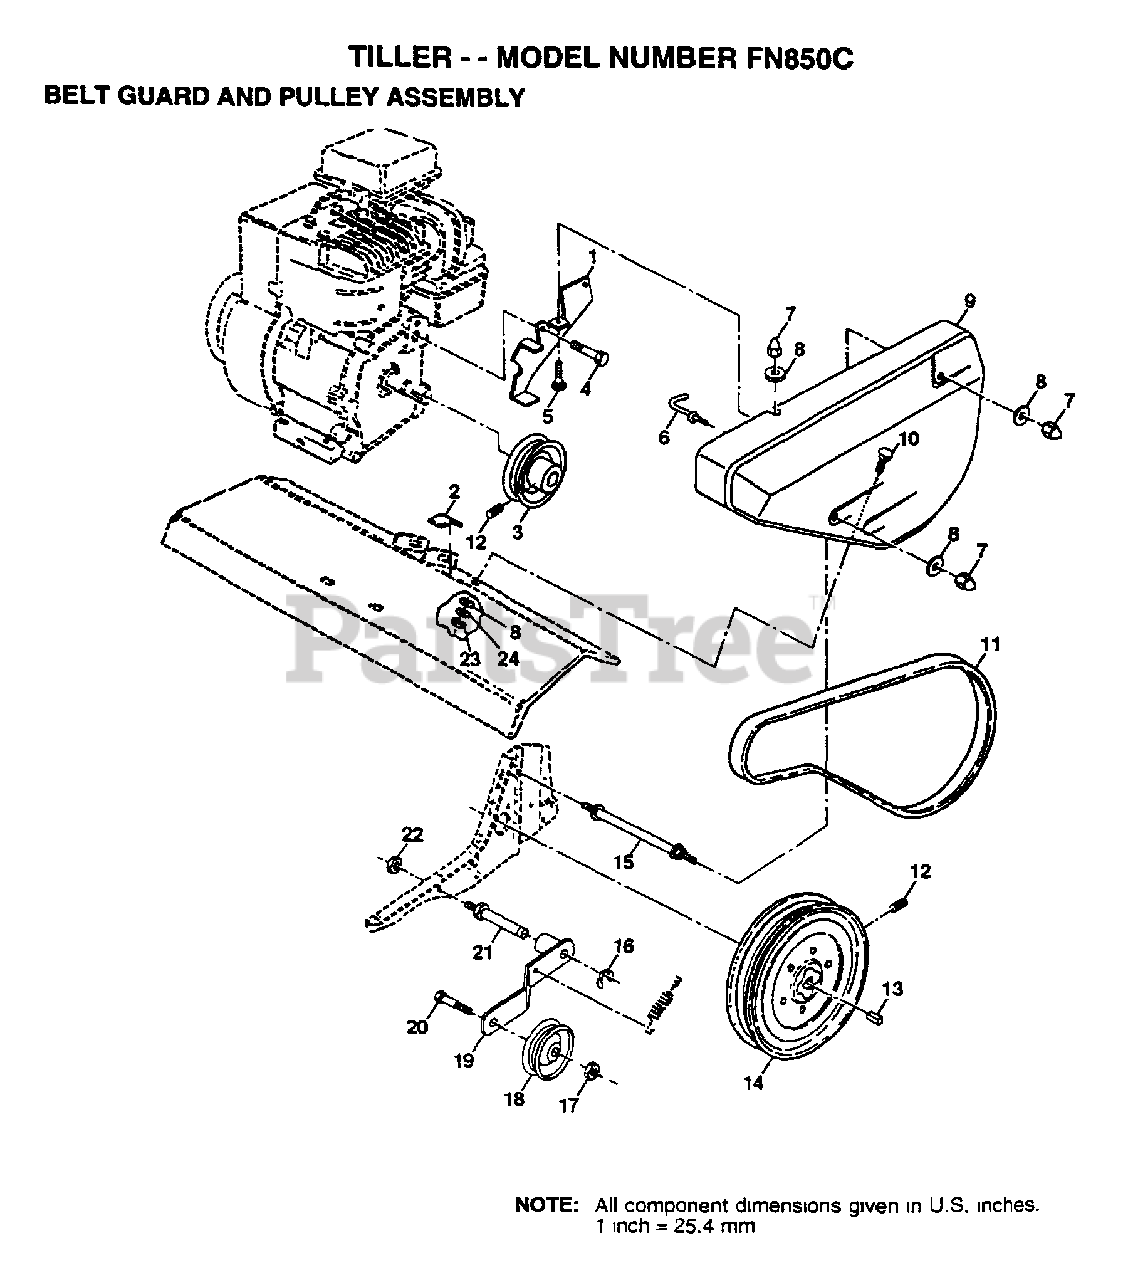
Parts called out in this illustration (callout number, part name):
2	PAD IDLER TI
3	ENGINE PULLEY
5	BOLT
7	NUT-CAP TI
8	WASHER
9	"GUARD, BELT"
10	BOLT T
11	V BELT STD
12	SET SCREW
13	KEY T
14	TRANS SHEAVE RT
15	BOLT TI
16	KLIP RING TI
17	NUT
19	IDLER ARM TI
21	SHAFT IDLER TI
22	JAM NUT TI
24	LOCKWASHER
